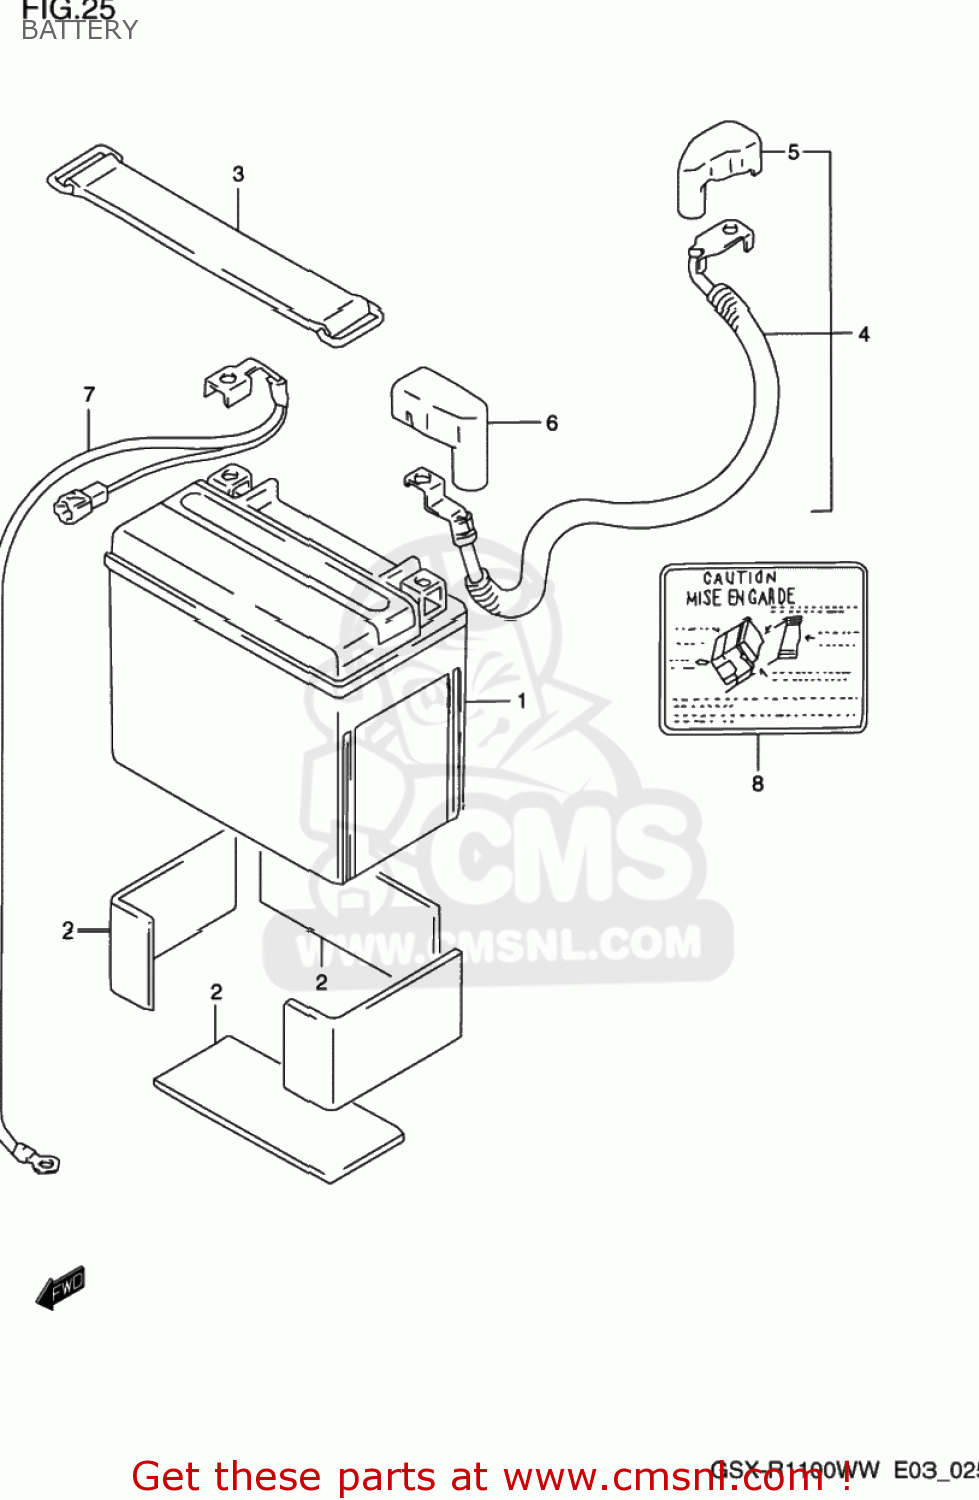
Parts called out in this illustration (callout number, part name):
1	BATTERY ASSEMBLY (12V) YTX
2	PROTECTOR(170X95X3.0)
3	BAND
4	WIRE,BATTERY PLUS
5	CAP,STARTER RELAY TERMINAL
6	CAP,BATTERY PLUS
7	WIRE,BATTERY MINUS
8	PLATE,BATTERY CAUTION
